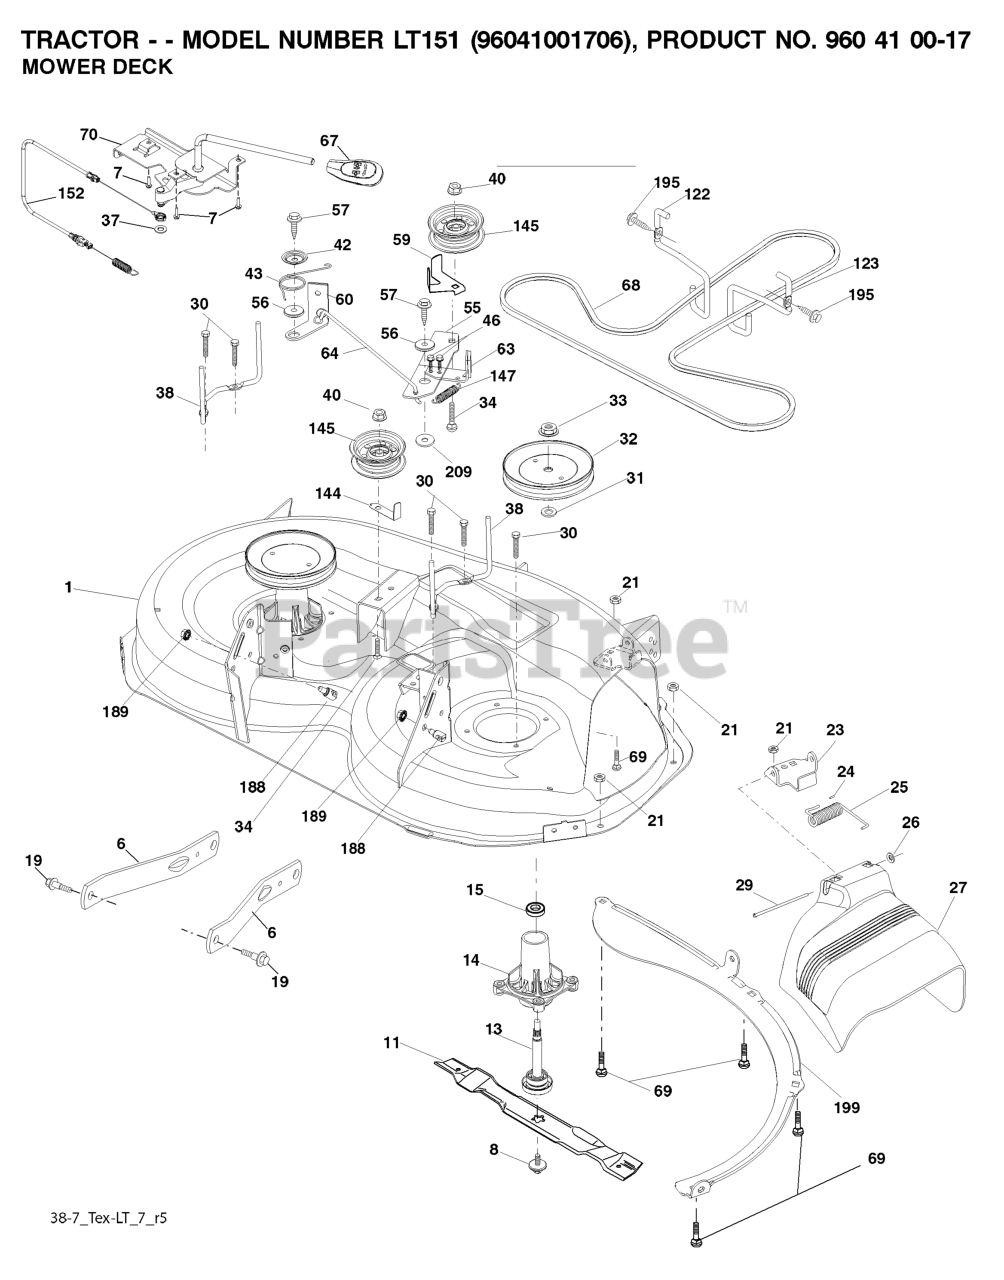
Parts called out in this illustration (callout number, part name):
1	HOUSING
6	ARM.SUSPENSION.MOWER.R
7	SCREW.#10 X 0.750.BOS
8	BOLT.WASHER.ASM.7/16-2
11	BLADE 38" PREMIUM
13	SHAFT.ASM.MDRL.N/GREASE.38
14	RP.HOUSING.MANDREL.4PT.
19	BOLT.SHOULDER
21	LOCKNUT
23	BRKT.DEFLECTOR.38"2005+
24	CAP-SLEEVE LT
25	SPRING.TORSION.DEFLECT
26	NUT PUSH M
27	SHIELD.DEFLECTOR.MWR.38-7/97CM
29	ROD.HINGE
30	SCREW, WASHER HEAD
31	WASHER.SPACER.MANDREL
32	PULLEY.MANDREL.5.0.PD.38"
33	NUT.FLANGE.LOCK.TOP
34	BOLT.3/8-16X1.50
37	WASHER
38	KEEPER BELT LH MANDREL
40	NUT LOCK FLG 3/8-16 UNC
42	SPRING.TORSION.BRAKE
43	SRPING.TORSION.RETAINE
46	SCREW.1/4-20X5/8
56	SPACER.RETAINER
57	SCREW 3/8-16X1
59	GUARD, BELT
60	ARM BRAKE MOWER RH 38"
63	RP ARM.BRAKE.MOWER.38"LH.TEX
64	LINK BRAKE
67	HANDLE.CLUTCH.CABLE.LT
69	BOLT
70	CLUTCH.ASM.MANUAL.LT.PRED
122	KEEPER BELT ENGINE LH
123	KEEPER BELT RH
144	KEEPER BELT
145	PULLEY.IDLER.48"PRIMARY
147	SPRING RETURN
152	CLUTCH CABLE
188	STUD.FASTNER.W/ANTI-ROTATE
189	NUT LOCK HEX FLANGE 5/16-18
195	SCREW, 3/8-16X3/4
199	BAFFLE.VORTEX.FRONT.38"
209	WASHER 12/32X2X10GA
